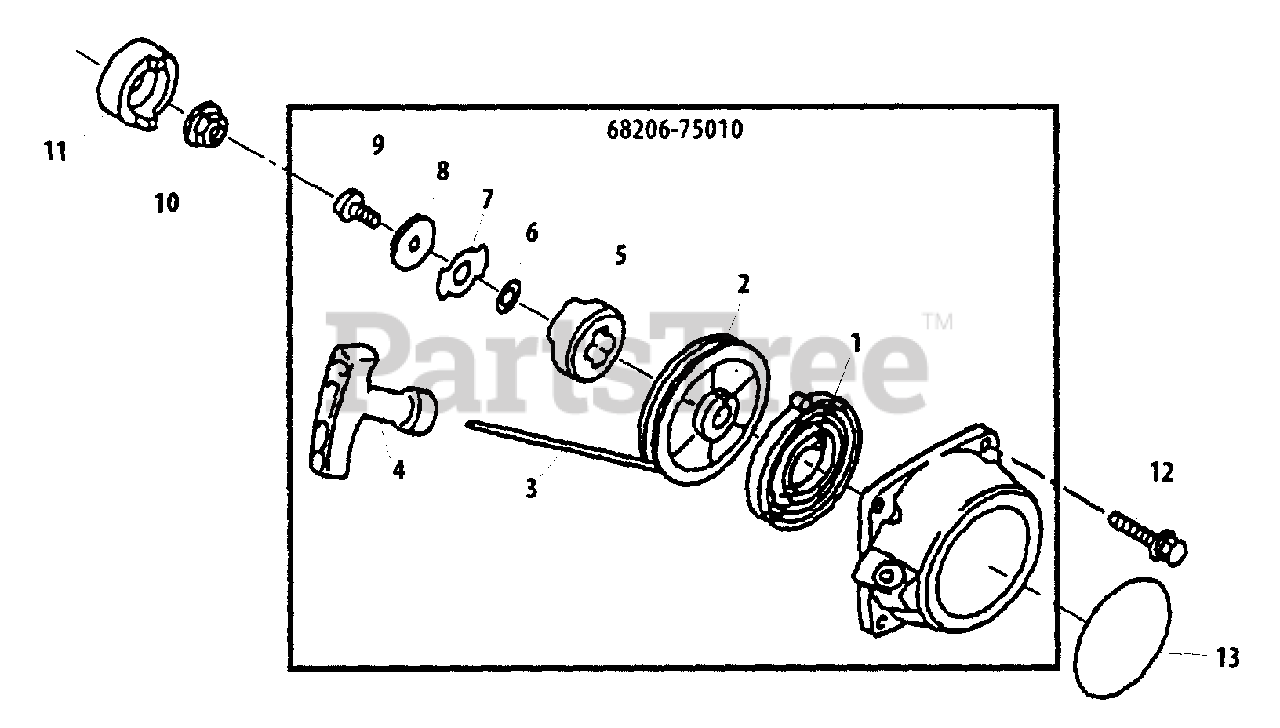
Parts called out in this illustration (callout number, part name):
1	SPRING, RECOIL
2	REEL
4	GRIP, STARTER
5	CAM
7	RETAINER
9	SCREW M8×1.25
10	NUT, FLANGE M10
11	PULLEY, STARTER
12	BOLT M5×20
13	LABEL, TRADE
68206-75010	STARTER ASSY, RECOIL
